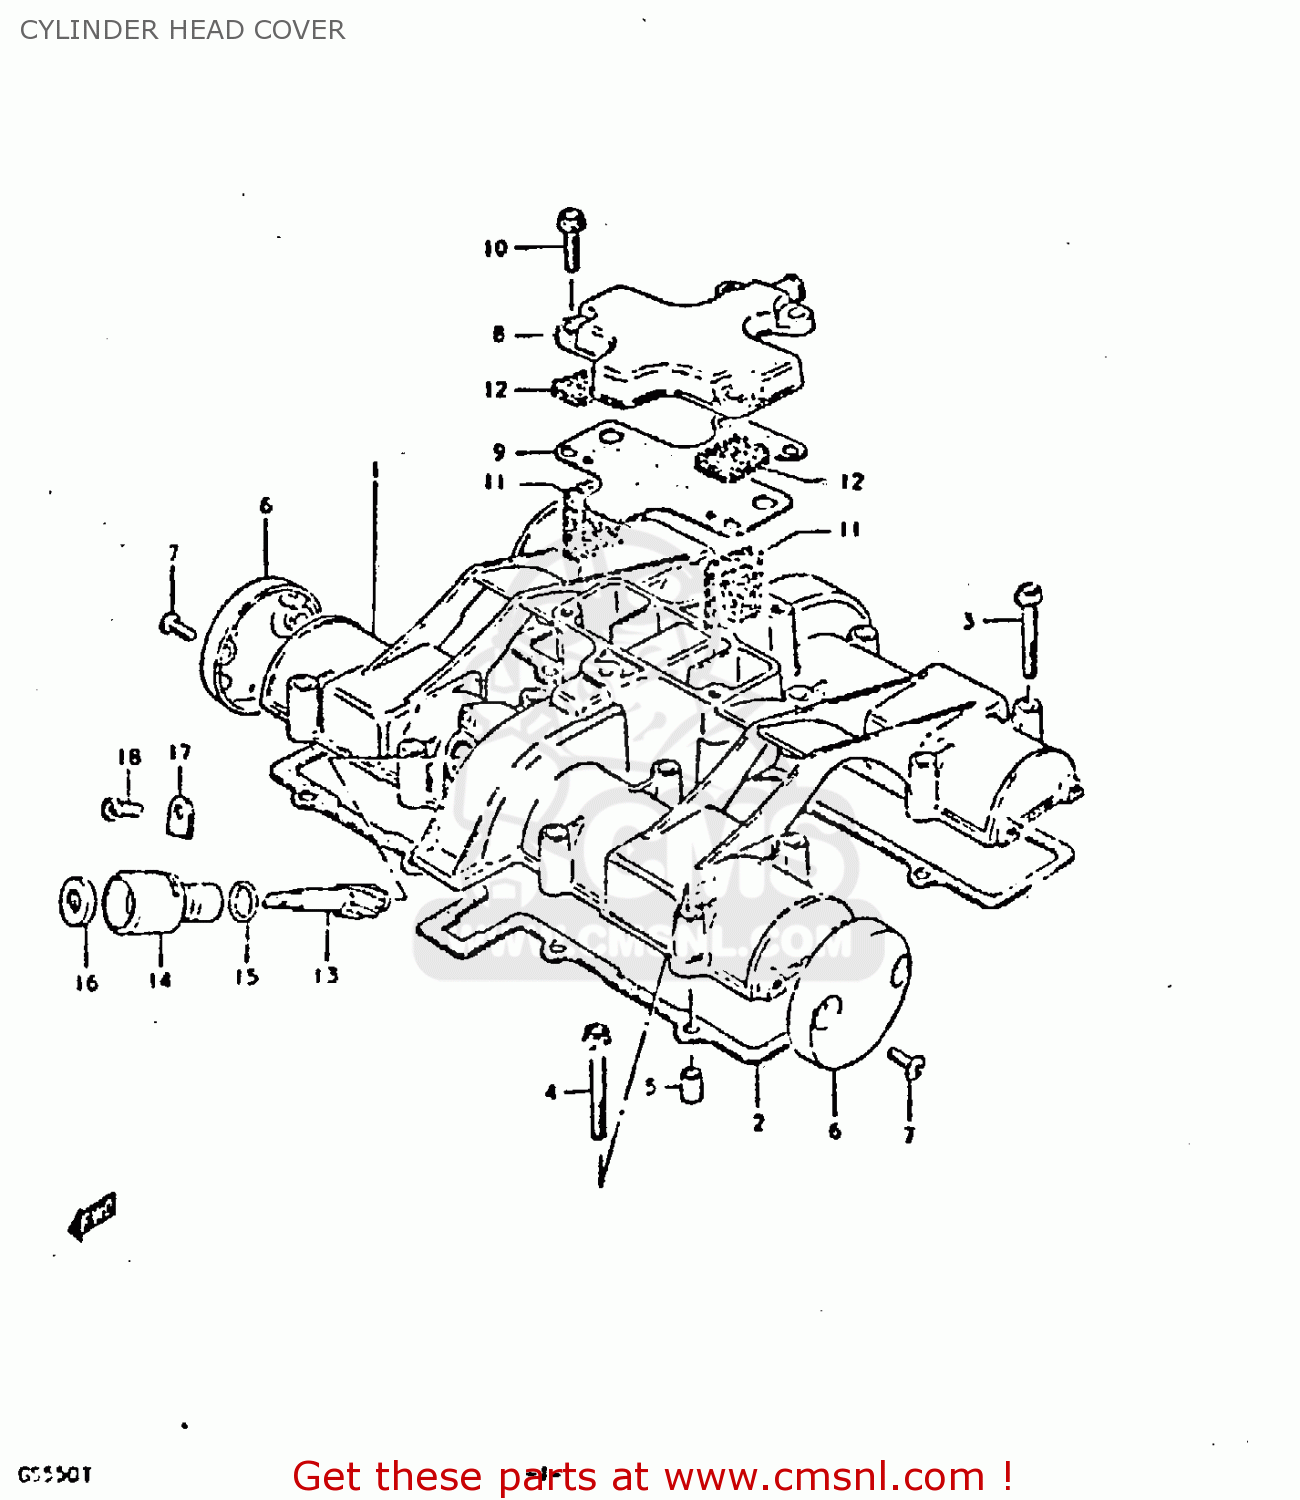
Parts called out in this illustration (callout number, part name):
1	COVER,CYLINDER HEAD
2	GASKET,CYLINDER HEAD COVER (MCA)
3	BOLT
4	BOLT,UNDER
5	PIN(6.2X8X11)
6	CAP,CYLINDER HEAD COVER
7	SCREW
8	COVER,BREATHER
9	GASKET (MCA)
10	BOLT,REAR
11	COVER,BREATHER
12	SEPARATOR,OIL BREATHER
13	GEAR,TACHOMETER DRIVEN
14	SLEEVE,TACHOMETER DRIVE
15	SEAL,TACHOMETER DRIVEN
16	SEAL,OIL(5X12X8)
17	PLATE,TACH DRIVE GEAR SLEEVE
18	SCREW(5X12)
